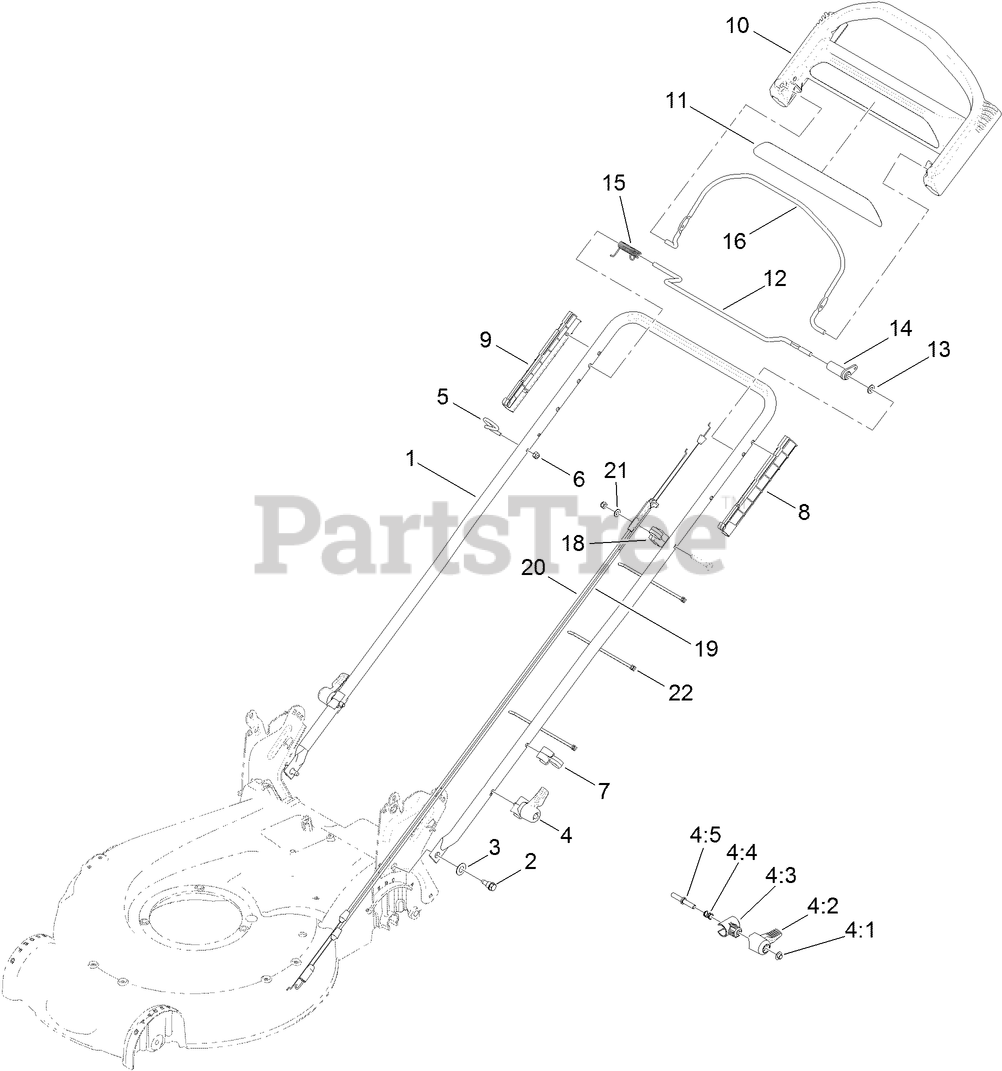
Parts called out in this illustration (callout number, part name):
2	BOLT-SHOULDER
3	WASHER-SPRING, CONICAL
4	QUICK RELEASE ASM
4:2	LEVER
4:3	ANCHOR-SPRING
4:4	SPRING-COMPRESSION
4:5	ROD-RELEASE
5	GUIDE-ROPE
6	NUT-LOCK, NI
7	GUIDE-CABLE
8	GUIDE-LH
9	GUIDE-RH
10	HANDLE-CONTROL
11	DECAL-HANDLE
13	WASHER-PLAIN
14	LEVER-TRACTION
19	CABLE-TRACTION
20	CABLE-BRAKE
21	WASHER-FLAT
22	TIE-CABLE
